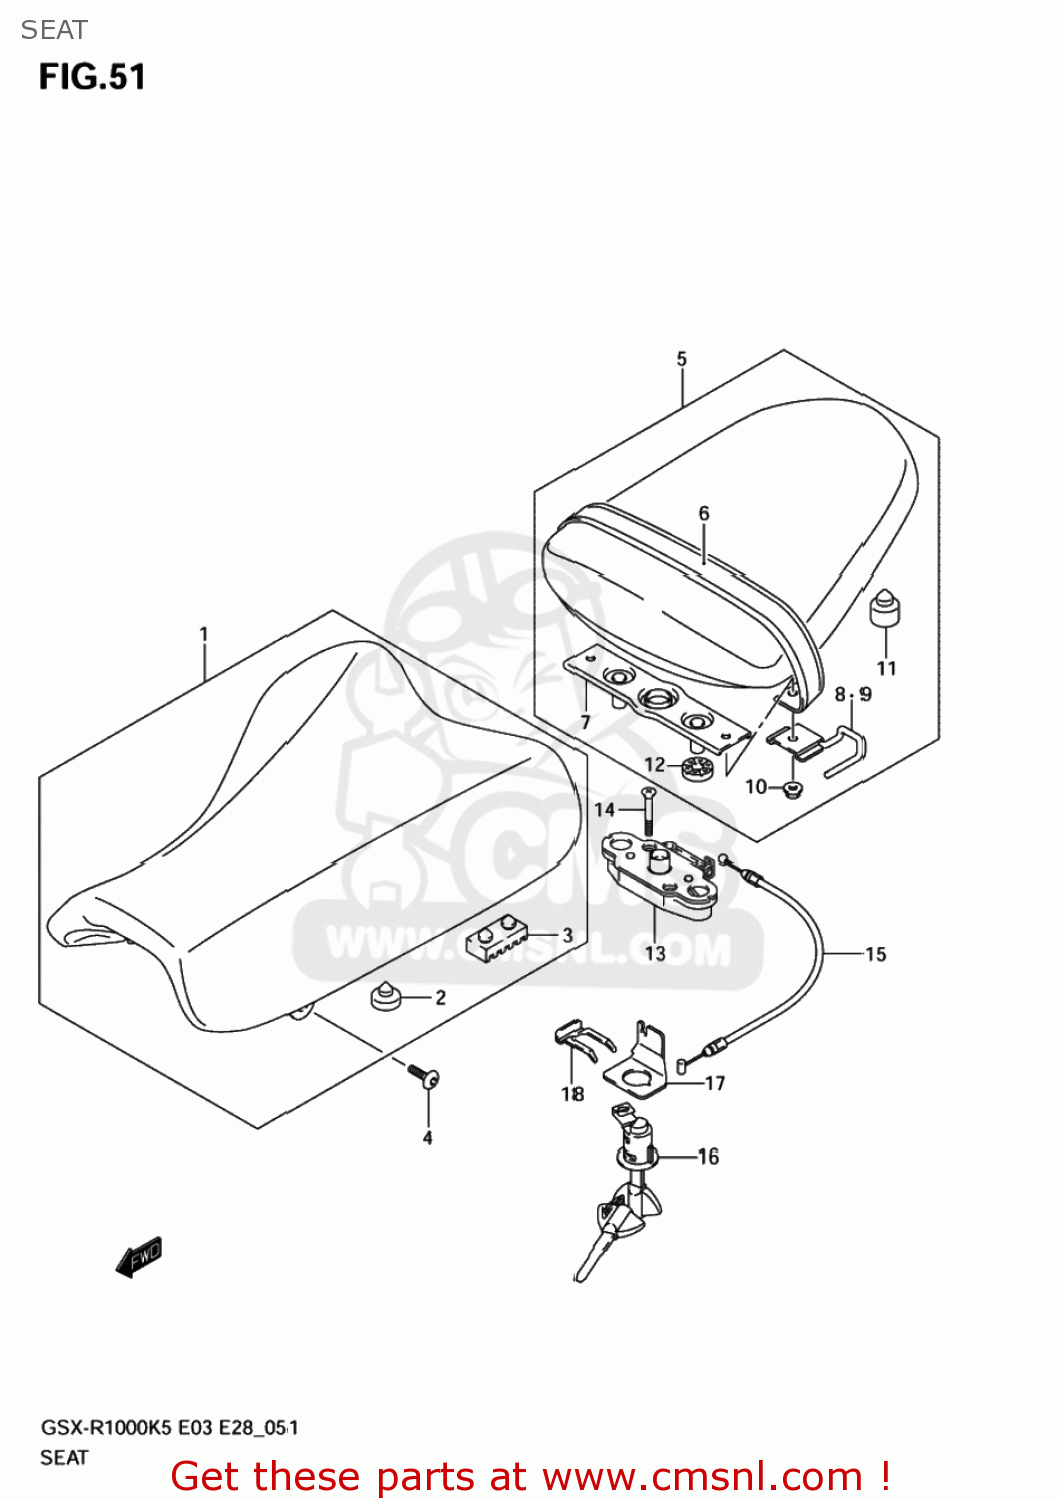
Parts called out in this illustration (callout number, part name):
1	SEAT ASSY
2	CUSHION
3	CUSHION,SIDE
4	SCREW(6X16)
5	SEAT ASSY,PILLION
6	BAND ASSY,SEAT
7	STRIKER
8	HOLDER,HELMET,R
9	HOLDER,HELMET,L
10	NUT
11	CUSHION
12	CUSHION
13	BRACKET,SEAT SUPPORT,RIGHT
14	SCREW
15	CABLE,SEAT LOCK CABLE
16	LOCK SET,SEAT
17	GUIDE,SEAT LOCK CABLE
18	PLATE,SEAT LOCK ASSY
